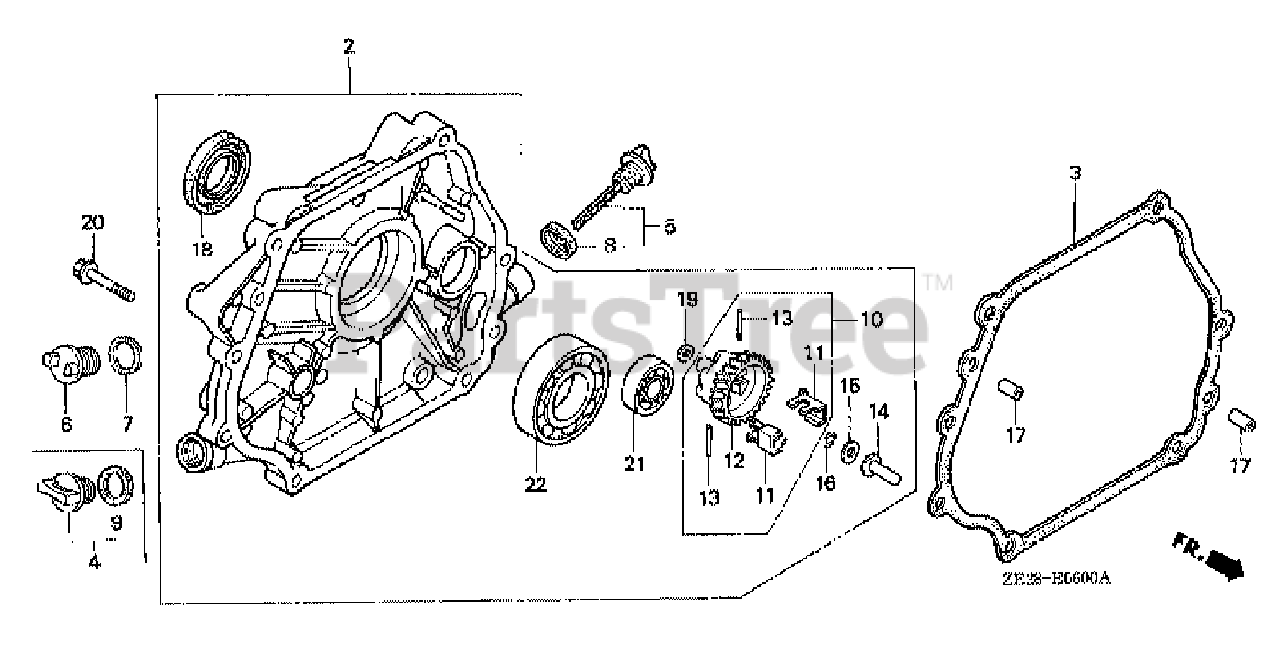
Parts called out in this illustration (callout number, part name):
2	COVER ASSY., CRANKCASE (Q-TYPE)(BALANCER)
3	GASKET, CASE COVER
4	CAP ASSY., OIL FILLER
5	CAP ASSY., OIL FILLER
6	CAP, OIL FILLER
7	GASKET, OIL FILLER CAP
8	GASKET, OIL FILLER CAP
9	GASKET, OIL FILLER CAP
10	GOVERNOR ASSY. (BALANCER)
11	WEIGHT, GOVERNOR
12	HOLDER, GOVERNOR WEIGHT
13	PIN, GOVERNOR WEIGHT
14	SLIDER, GOVERNOR
15	WASHER (6X16)
16	CLIP, GOVERNOR HOLDER
17	PIN, DOWEL (8X12)
18	OIL SEAL (30X46X8)
19	WASHER, PLAIN (6MM)
20	BOLT, FLANGE (8X35)
21	BEARING, RADIAL BALL (6202)
22	BEARING, RADIAL BALL (6206)
